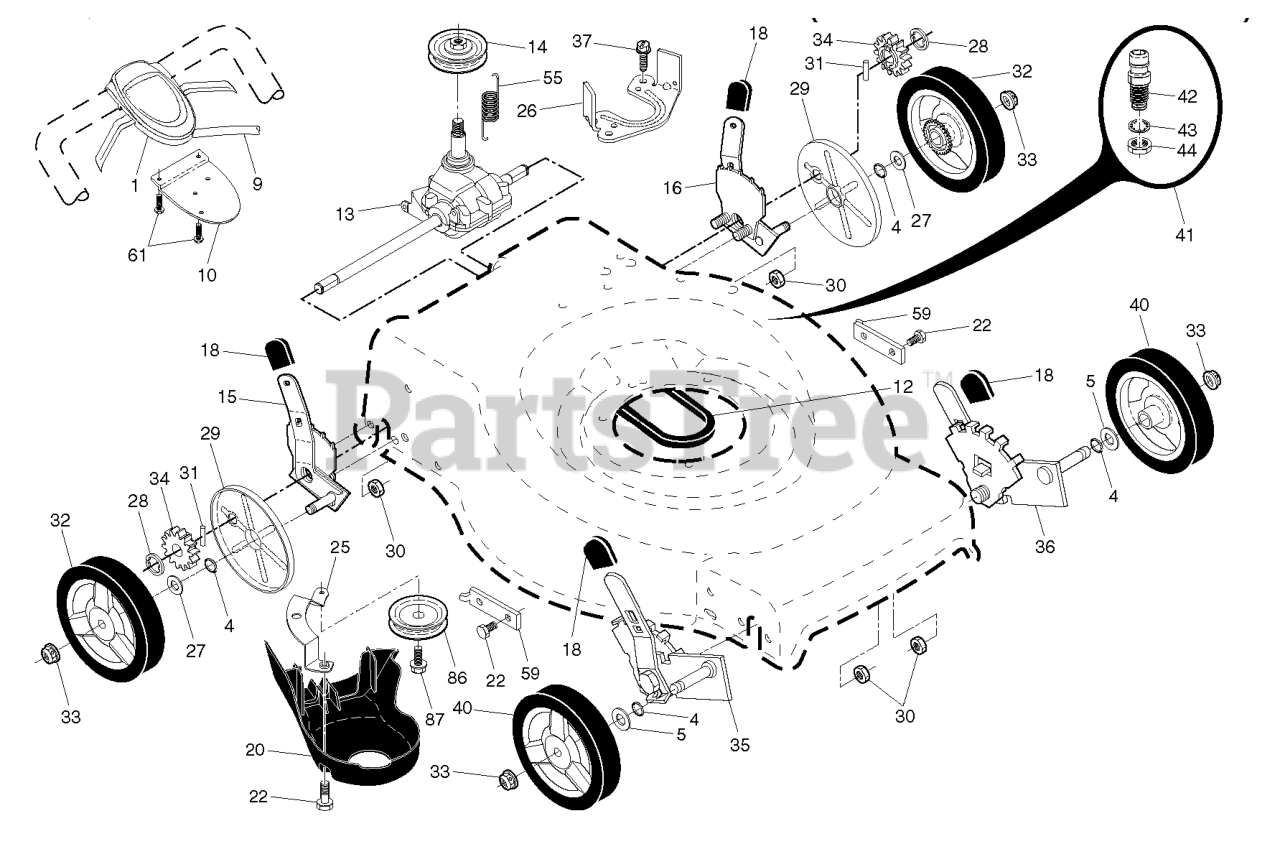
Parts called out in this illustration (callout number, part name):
1	CONTROL.DR.AW2.22+.BLK.GEN
4	O-RING..070X.487.NEOPRENE
5	WASHER.FLAT.1/2
10	BRACKET DUAL TRIGGER CONTROL
12	BELT V3L 35.42, CLUTCHING COVE
13	TRANSMISSION.22+AWD.WALK.MOWER
14	PULLEY.DRIVE.SM.AWD/RWD
15	ADJUSTER.ASM.22+FGD.RF /AWD RT
16	ADJUSTER.ASM.22+FGD.LF /AWD LT
18	SELECTOR KNOB
20	COVER.REAR.DRIVE.22+2013
22	BOLT.5/16HEX.WHS.HD
25	BRACKET.DRIVE.COVER.RGD.
26	BRACKET.TRANS.BELTKEEP.21 RWD
27	WASHER FLUT
28	E-RING 7/16 RE
29	COVER.DUST.WHEEL.INNER.WALK
30	NUT.HEX.FLANGE.1/4
31	PAWL, DRIVE
32	WHEEL.8X1.75.3SPK.RAD3.GREY
33	NUT.HEX.FLANGE.3/8-16.LO(3 2)
34	PINIION.14.TOOTH.RGD
35	ADJUSTER.ASM.9POS.LW.RL/RGD.FR
36	ADJUSTER.ASM.9POS.LW.RR/RGD.
40	WHEEL & TIRES ASSY, FRONT
41	KIT.WASH-OUT.PORT.ZINC.WALK
42	WASHOUT.PORT.ZINC.RGD.22+
43	WASHER.LOCK.INTERNAL.TOOTH
44	LOCKNUT.HEX.WITH.O-RING
55	SPRING.RETURN.AUTO.
59	BRACKET.SUPPORT.22+RWGD.BZP
61	SCREW, PHILLIPS HEAD 10 X 5/8
86	PULLEY.RWD.IDLER.DBL SEAL
